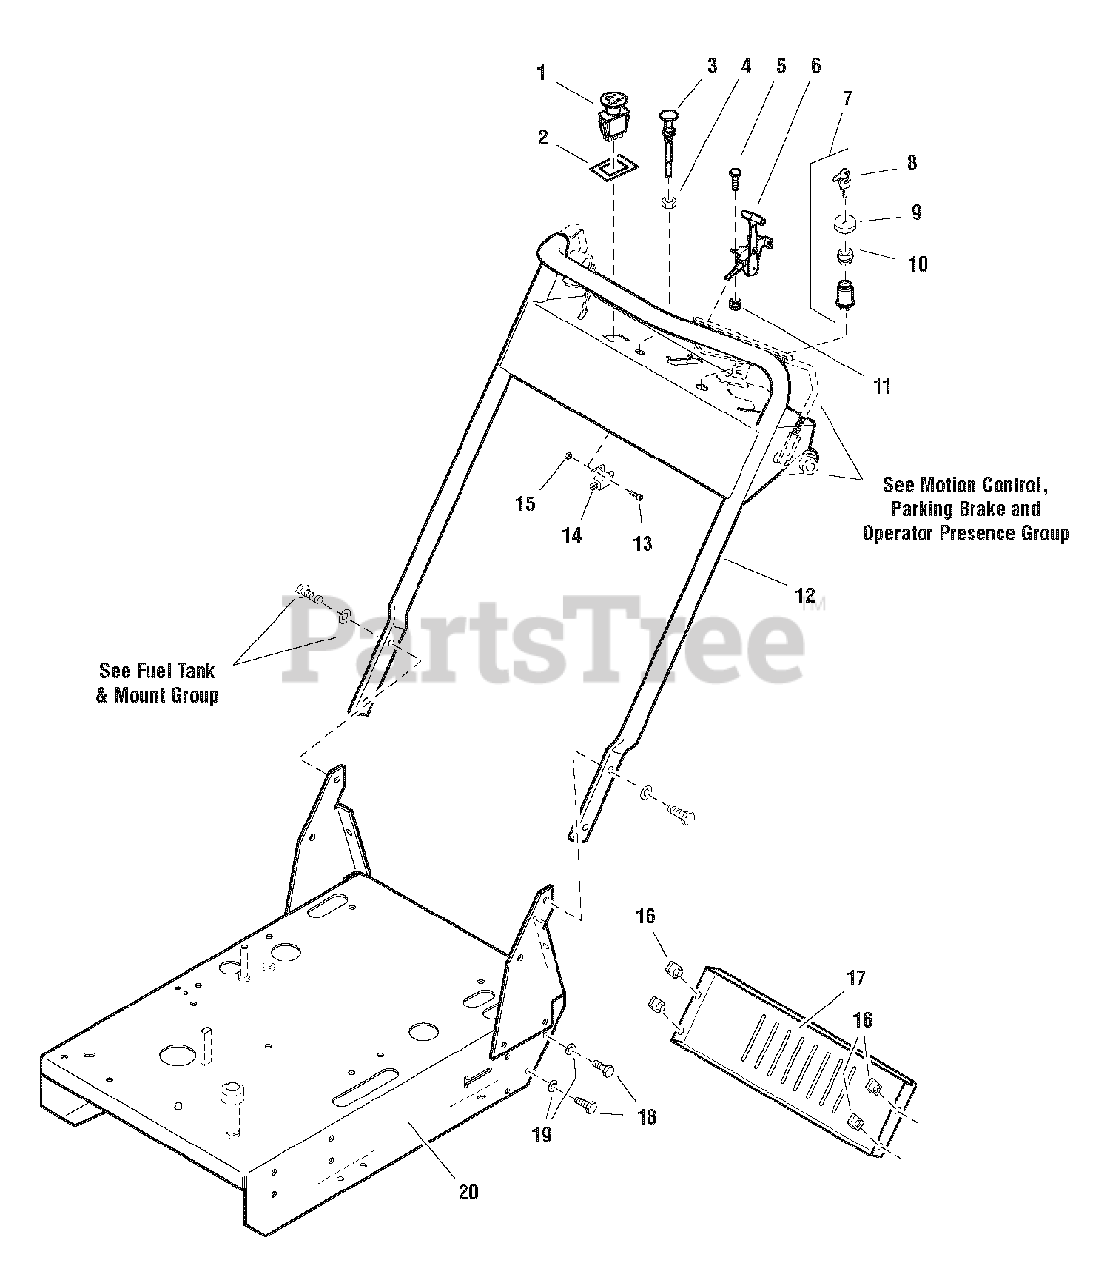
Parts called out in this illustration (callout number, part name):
1	SWITCH, PTO
2	SWITCH RETAINER RING
3	CABLE, Choke Control
4	NUT, Hex, 3/8-24
5	CAPSCREW, Hex Head, 1/4-20 x 3/4
6	CABLE, Throttle Control
7	SWITCH, Ignition, Complete (includes Ref 7 - 9)
8	KEY, Ignition, Molded (set of 2)
9	COVER, PLASTIC, SNAP ON
10	PLASTIC NUT
11	NUT, Hex Nylon Lock, 1/4-20
12	HANDLE BAR ASSEMBLY, Complete (includes decals)
12	HANDLE BAR ASSEMBLY (Red)
13	SCREW, Phillips Hd, #10-24 x 1/2
14	SWITCH, NC
15	NUT, Hex, #10-24
16	BODY CLIP, 5/16-18
17	REAR SHIELD
18	BOLT, 5/16-18 X 3/4 GD5
19	WASHER, 5/16
20	ENGINE DECK ASSEMBLY
